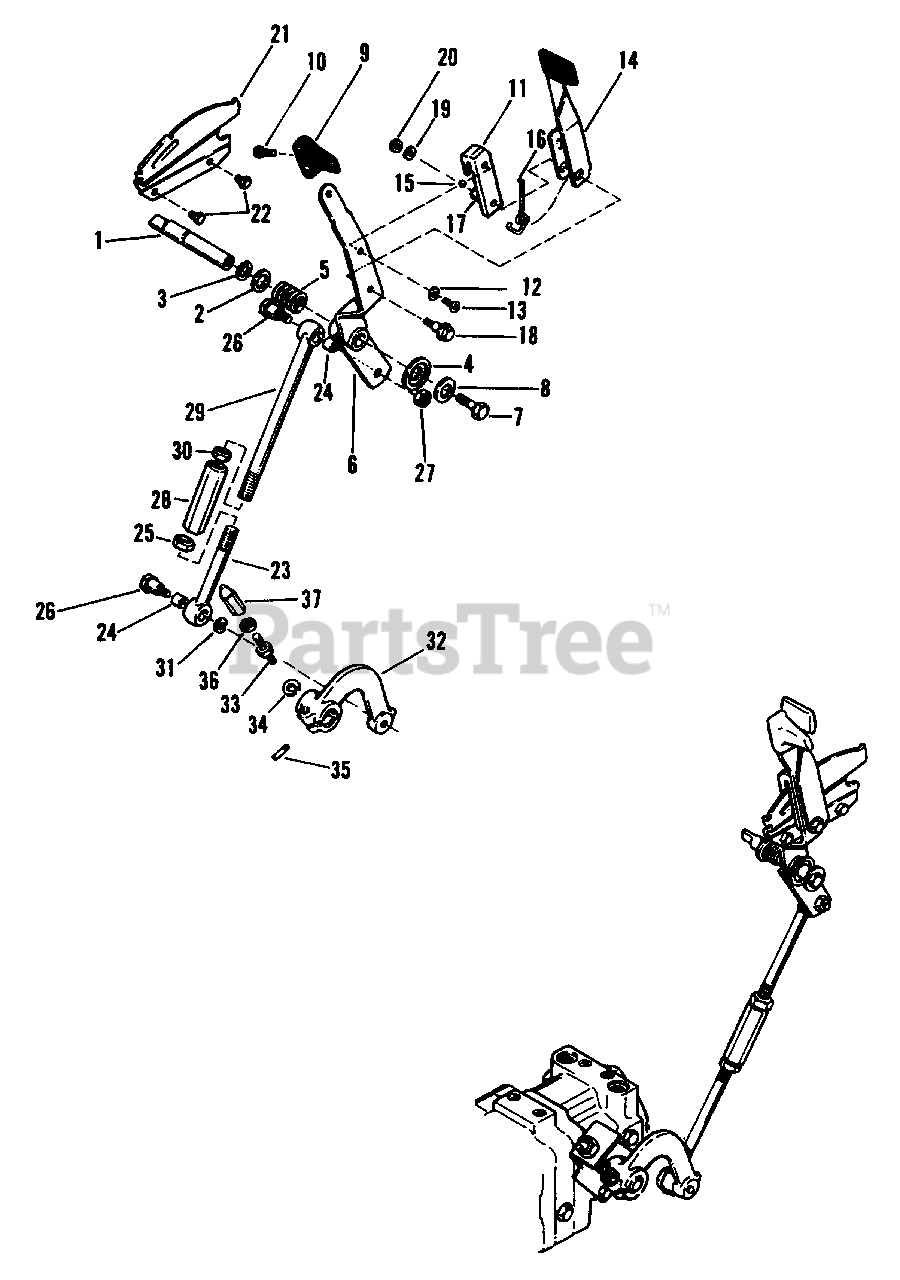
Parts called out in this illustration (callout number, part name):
1	Pivot Shaft
3	Retaining Ring
6	Lever Assembly
7	Hex Capscrew, 3/8"-16 x 1-1/4" lg.
10	Thread Forming Screw, 1/4"-20 x 3/4" lg.
11	Stop Clamp
12	Lock Washer, 1/4"
13	Phillips Screw 1/4"-20 x 1/2" lg.
18	Shoulder Bolt
19	Plain Washer, 1/4"
20	Hex Nut, Lock, 1/4"-20
22	Taptite Screw, 1/4"-20 x 3/8" lg.
25	Hex Nut, Jam, 1/2"-20
26	Shoulder Bolt
27	Hex Nut Full Lock, 3/8"-16
28	Turnbuckle
30	Hex Jam Nut, L.H. 1/2"-20
34	Lock Washer, 3/8"
36	Nut, 3/8"-16
